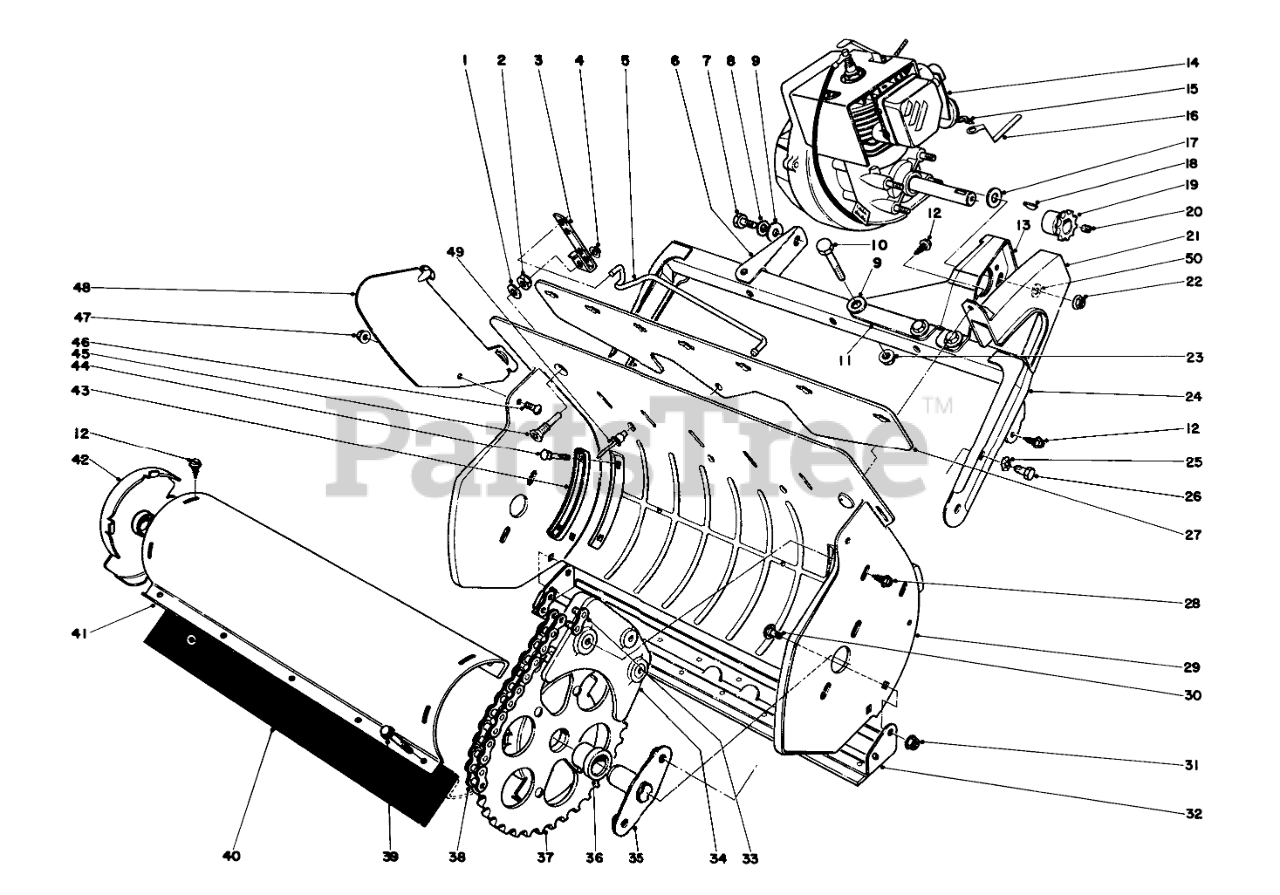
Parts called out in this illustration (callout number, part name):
1	WASHER-FLAT
2	NUT-LOCK, NI
3	Bracket-Vane Adj.
4	NUT-SPEED
5	Linkage Vane Adj.
6	Bracket
7	SCREW-HH
8	WASHER-LOCK/EXT
9	WASHER-FLAT
10	SCREW-HH
11	Bracket Engine
12	SCREW-HWHTF
13	Bracket Engine
14	Engine Mod. # AH520 Type No. 1401 H
15	Cotter Pin
16	Choke Strap
17	WASHER-PLAIN
19	SPROCKET
20	SCREW-SET, HSH
21	Chain Guard
22	NUT-HHF
23	NUT-LOCK, HHF
24	Frame Assembly
25	Washer
26	Screw
27	Vane Mount
28	Screw
29	Housing
30	SCREW-CARRIAGE
31	NUT-KEPS
32	Skid
33	LINK-CONNECTING, NO. 35
34	Stripper
35	Rotor Shaft
36	ROTOR BUSHING
37	End Cap Assembly L.H. (Incl. Ref. #36)
38	CHAIN
39	Screw
40	ROTOR BLADE
41	ROTOR SHELL
42	End Cap Assembly R.H. (Incl. Ref. # 36)
43	Handle Plate
44	SCREW-CARR
45	Screw
46	SCREW-PTH
47	NUT-LOCK, FLANGE
48	Vane
49	Pop Pivot
50	Lockwasher
